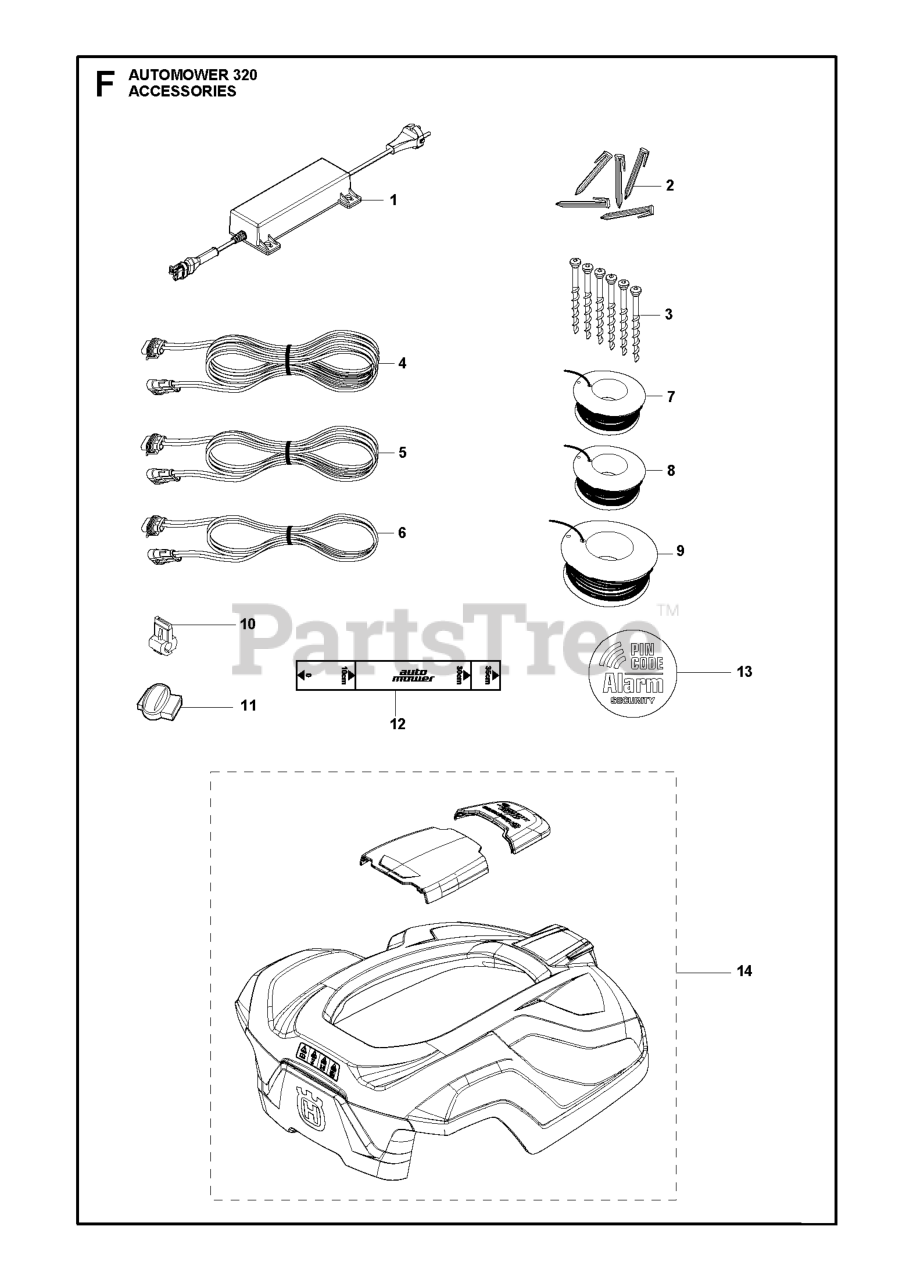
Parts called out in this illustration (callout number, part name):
2	STAPLE 100 PCS, BLISTER
2	STAPLE 100 PCS
3	SCREW KIT CS
3	SCREW 3 PCS, BLISTER PACK
4	CABLE ASSY LOW VOLTAGE CABLE
5	CABLE ASSY LOW VOLTAGE CABLE
6	CABLE ASSY LOW VOLTAGE CABLE
7	WIRE BOUNDARY 150M
7	WIRE 150M, BLISTER
8	WIRE 250M
9	WIRE 500M
10	BRAKER
10	CONNECTOR 5 PCS, BLISTER
11	COUPLER SPLICER, 5 PCS,
11	COUPLER SPLICER, 100 PCS
11	SPLICE KIT
12	RULER / CENTIMETERS
13	LABEL SECURITY
